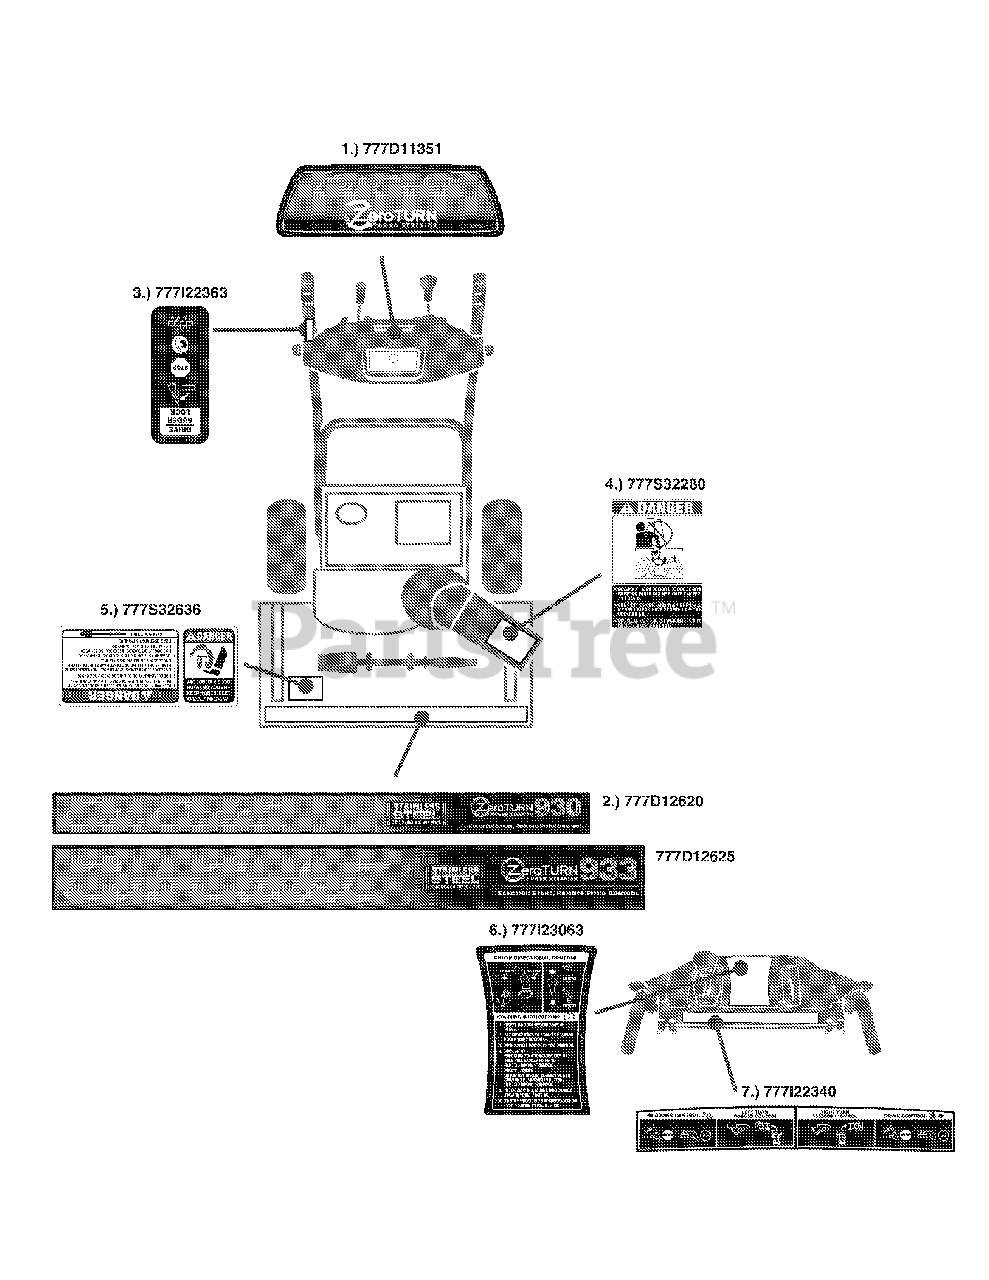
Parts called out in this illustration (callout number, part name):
1	Cub Cadet Panel Label
2	Auger Housing Label 30" Units
2	Auger Housing Label 33" Units
3	Auger Drive Label
4	Chute Danger Label
5	Auger Housing Danger Label
6	Handle Panel Chute Instructions
7	Handle Panel Drive Instructions
